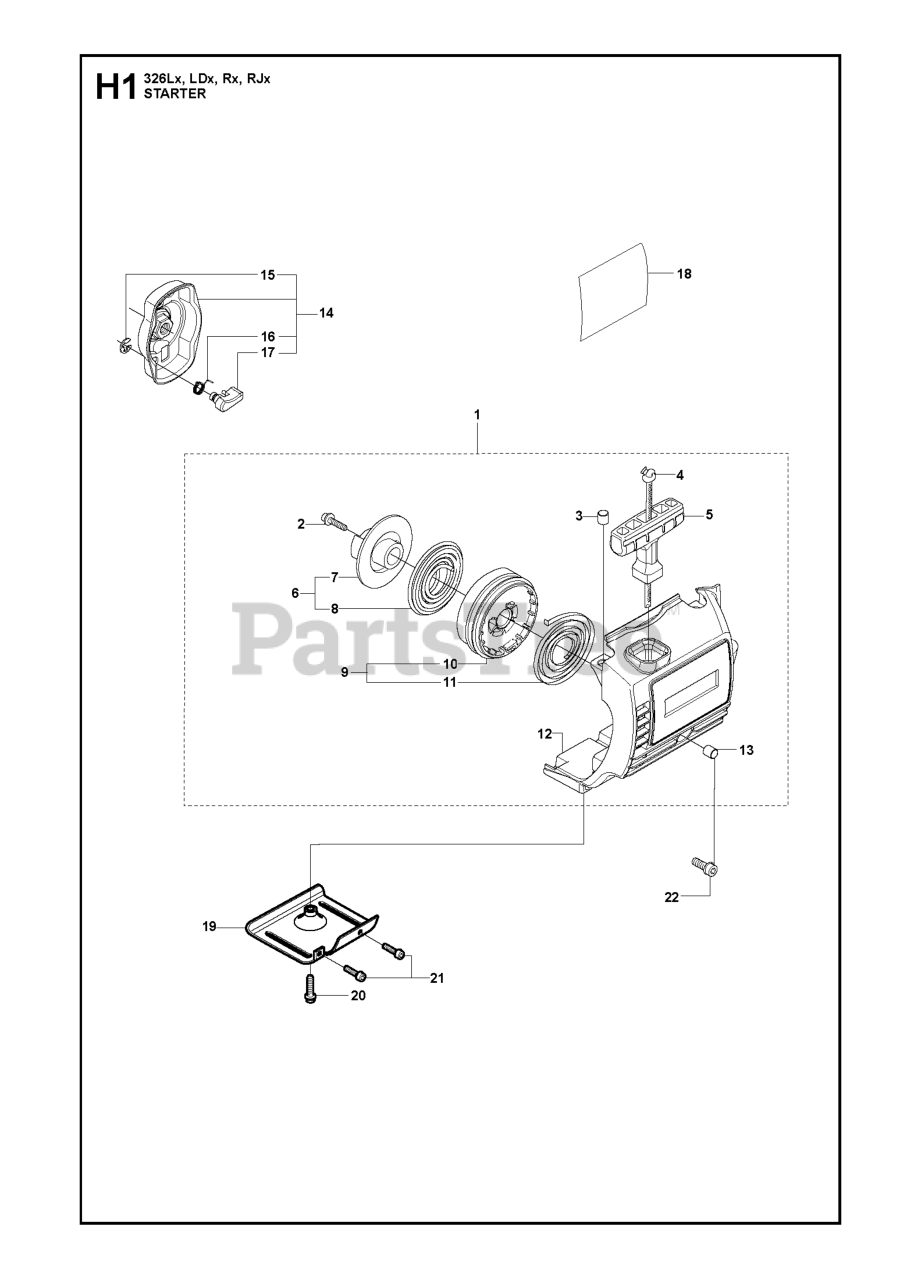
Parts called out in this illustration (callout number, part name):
1	RP STARTER ASSY
3	SPACING SLEEVE
4	STARTER ROPE
5	STARTER HANDLE
7	DRIVER PULLEY
8	SPRING - DRIVER
9	STARTER PULLEY
10	STARTER PULLEY
12	RP STARTER HOUSING
13	SPACING SLEEVE
14	STARTER PAWL BRIDGE
17	STARTER PAWL
18	DECAL DEVICE
18	DECAL, STARTER HOUSING
19	PLATE
22	SCREW
